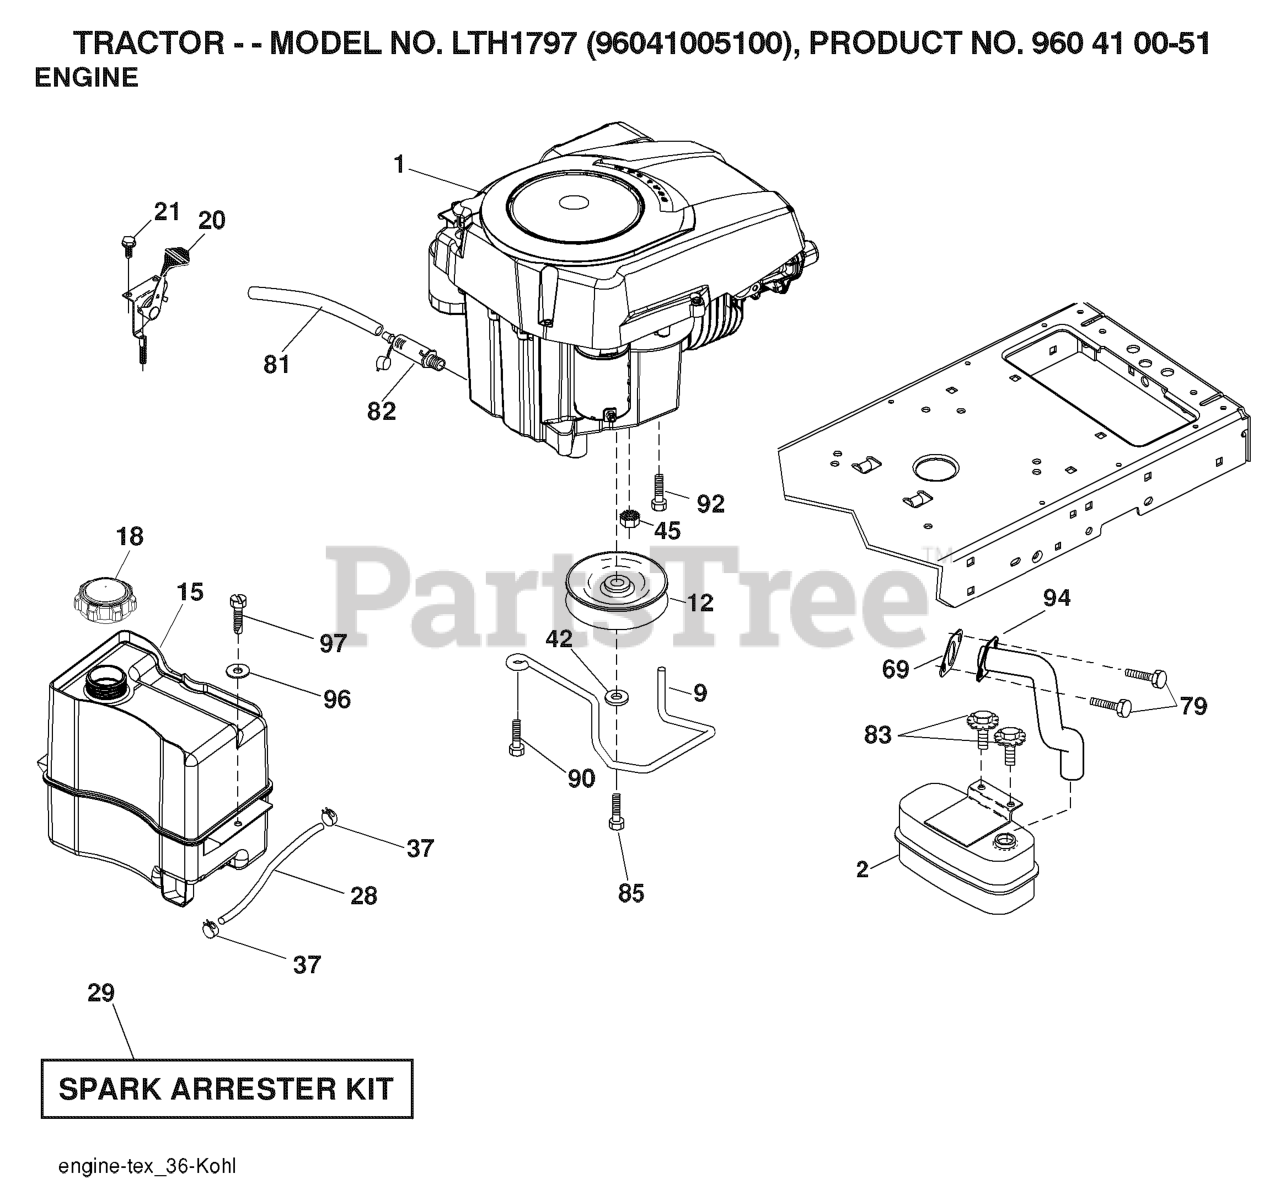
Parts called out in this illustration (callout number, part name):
2	MUFFLER.SINGLE.CYL.KOHL/B&S
9	KEEPER.BELT.ENGINE.4.2
12	PULLY ENGINE
15	RP TANK FUEL FRT 1.5 GAL
18	FUEL CAP
20	CONTROL.TH/CK.C.
21	SCREW
28	LINE.FUEL.20
29	KIT.SPARK ARRESTOR 794945 B&S
37	HOSE CLAMP
42	LOCKWASHER
43	BOLT HEX 7/16-20X4-1/4"
45	NUT
69	GASKET.EXHAUST.KOHLER
79	SCREW.SOCKET HD.5/16-1
81	TUBE, DRAIN OIL ASM.
82	PLUG DRAIN OIL EASY
83	BOLT.5/16-18UNCX3/4 W/SEMS.BLK
90	SCREW 3/8-16X1
92	SCREW 3/8-16X1
94	RP.TUBE.EXHAUST.KOHL.COURAGE
97	SCREW HEXWSHR 1/4-20X3/4
